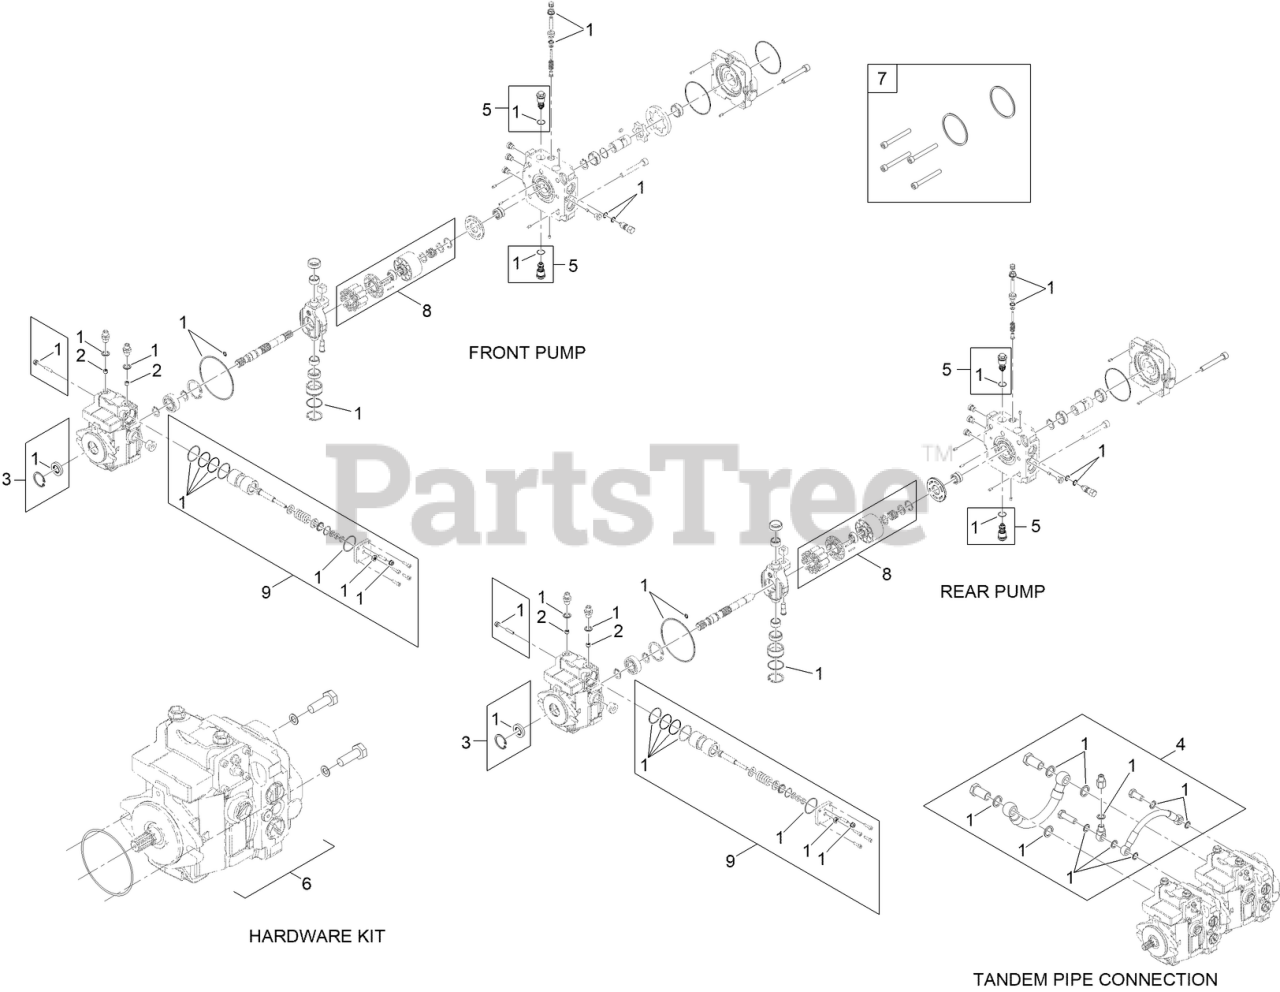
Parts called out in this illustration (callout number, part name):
1	SEAL KIT
2	SPACER-JET
3	SHAFT SEAL KIT
4	TANDEM CONNECTION PIPE KIT
5	VALVE-RELIEF,
6	HARDWARE KIT
7	BOLT KIT
8	ROTATING GROUP KIT
9	HYD SERVO CONTROL KIT
